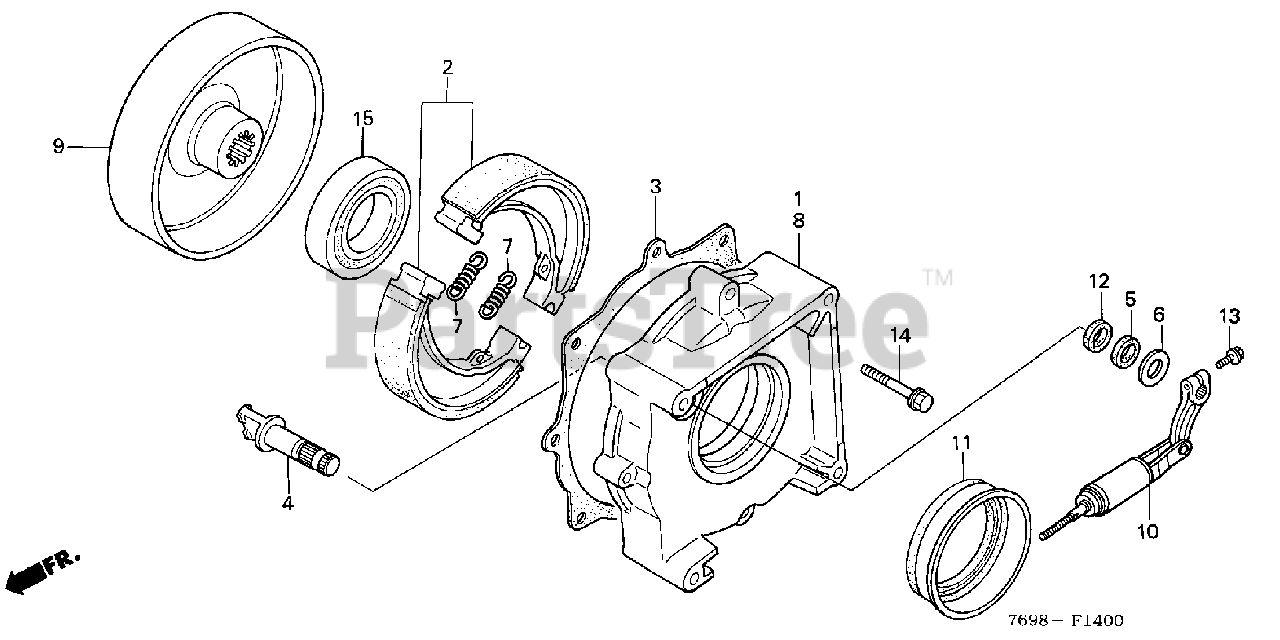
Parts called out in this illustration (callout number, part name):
1	PANEL, R. BRAKE
2	SHOE KIT, BRAKE
3	GASKET, BRAKE PANEL
4	CAM, BRAKE
5	DUST SEAL, BRAKE CAM
6	WASHER, BRAKE CAM
7	SPRING, RR. BRAKE SHOE
8	PANEL, L. BRAKE
9	DRUM, BRAKE
10	ARM, BRAKE
11	DUST SEAL (37X58X9)
12	DUST SEAL (17X23X3)
13	BOLT, FLANGE (8X25)
14	BOLT, FLANGE (8X40)
15	BEARING, RADIAL BALL (6007)
